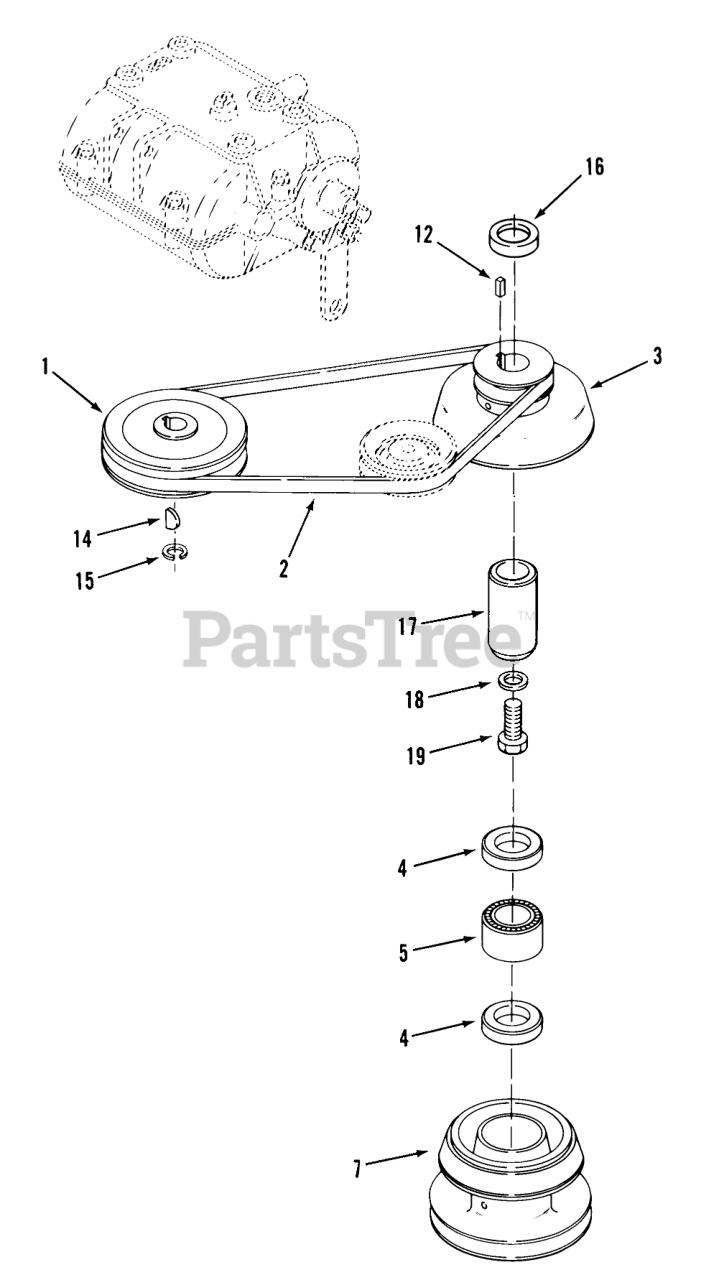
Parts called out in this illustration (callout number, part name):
1	PULLEY
2	V-BELT
3	Pulley-Engine
4	SEAL-OIL
5	BRG-NEEDLE OPEN END
7	Assy Pulley Mwr Dr
14	Key
15	SNAP RING- 5/8 EXT
16	TUBE-SPACER
17	Bearing Race
18	WASHER
19	HEX HD CAP SCREW
